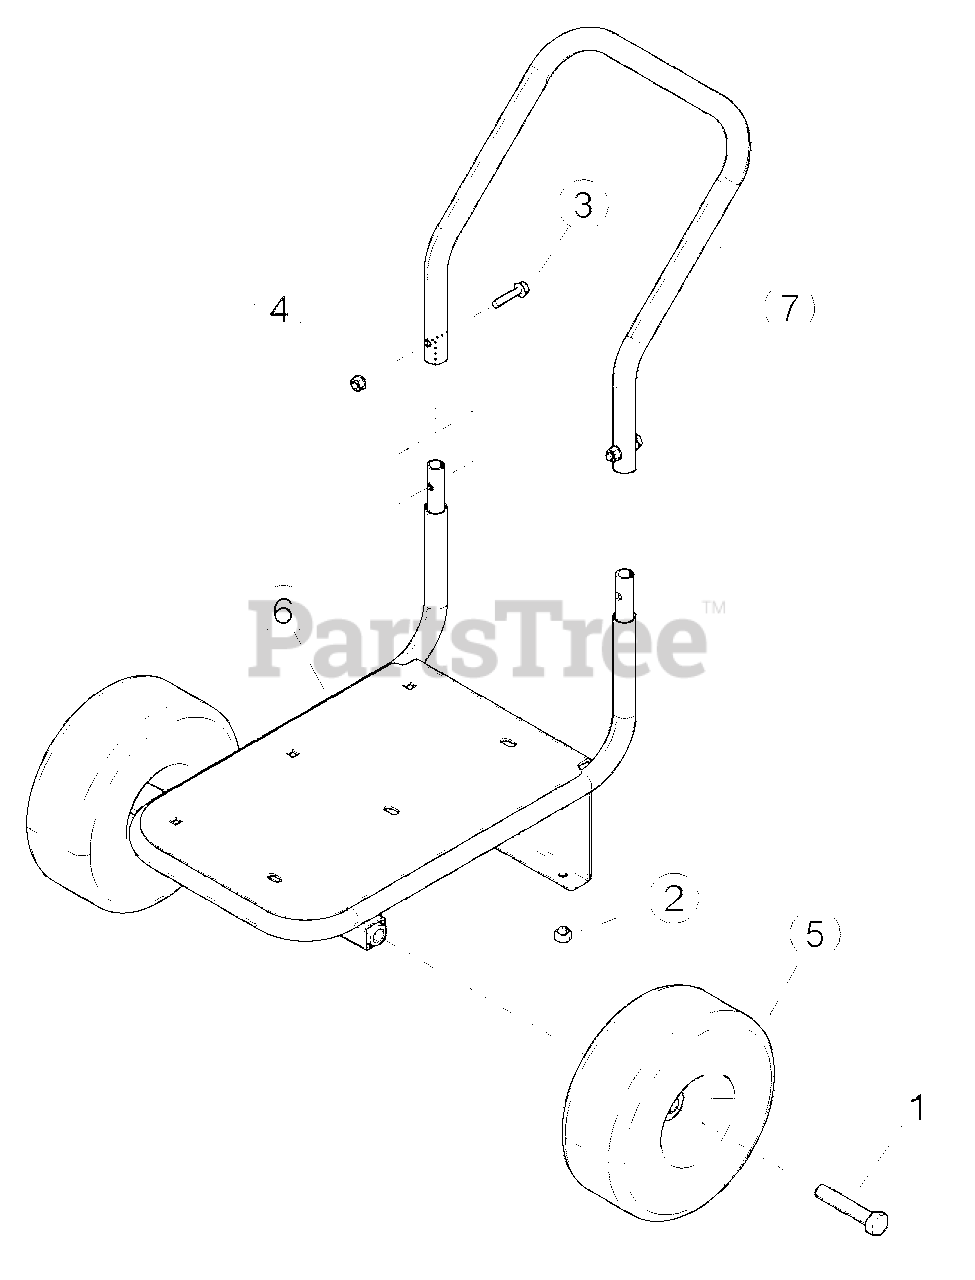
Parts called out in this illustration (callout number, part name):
1	BOLT, 5/8 X 3-1/4 HEX GR5 ZP
2	BUMPER, RUBBER
3	BOLT, 5/16 X 1-1/2 FLANGE NC
4	NUT, 5/16-18 NYLOCK FLANGE
5	ASSEMBLY, 410/350-4 FLAT-FREE WHEEL
6	WELDMENT, AXLE FRAME
7	HANDLEBAR, CHIPPER
